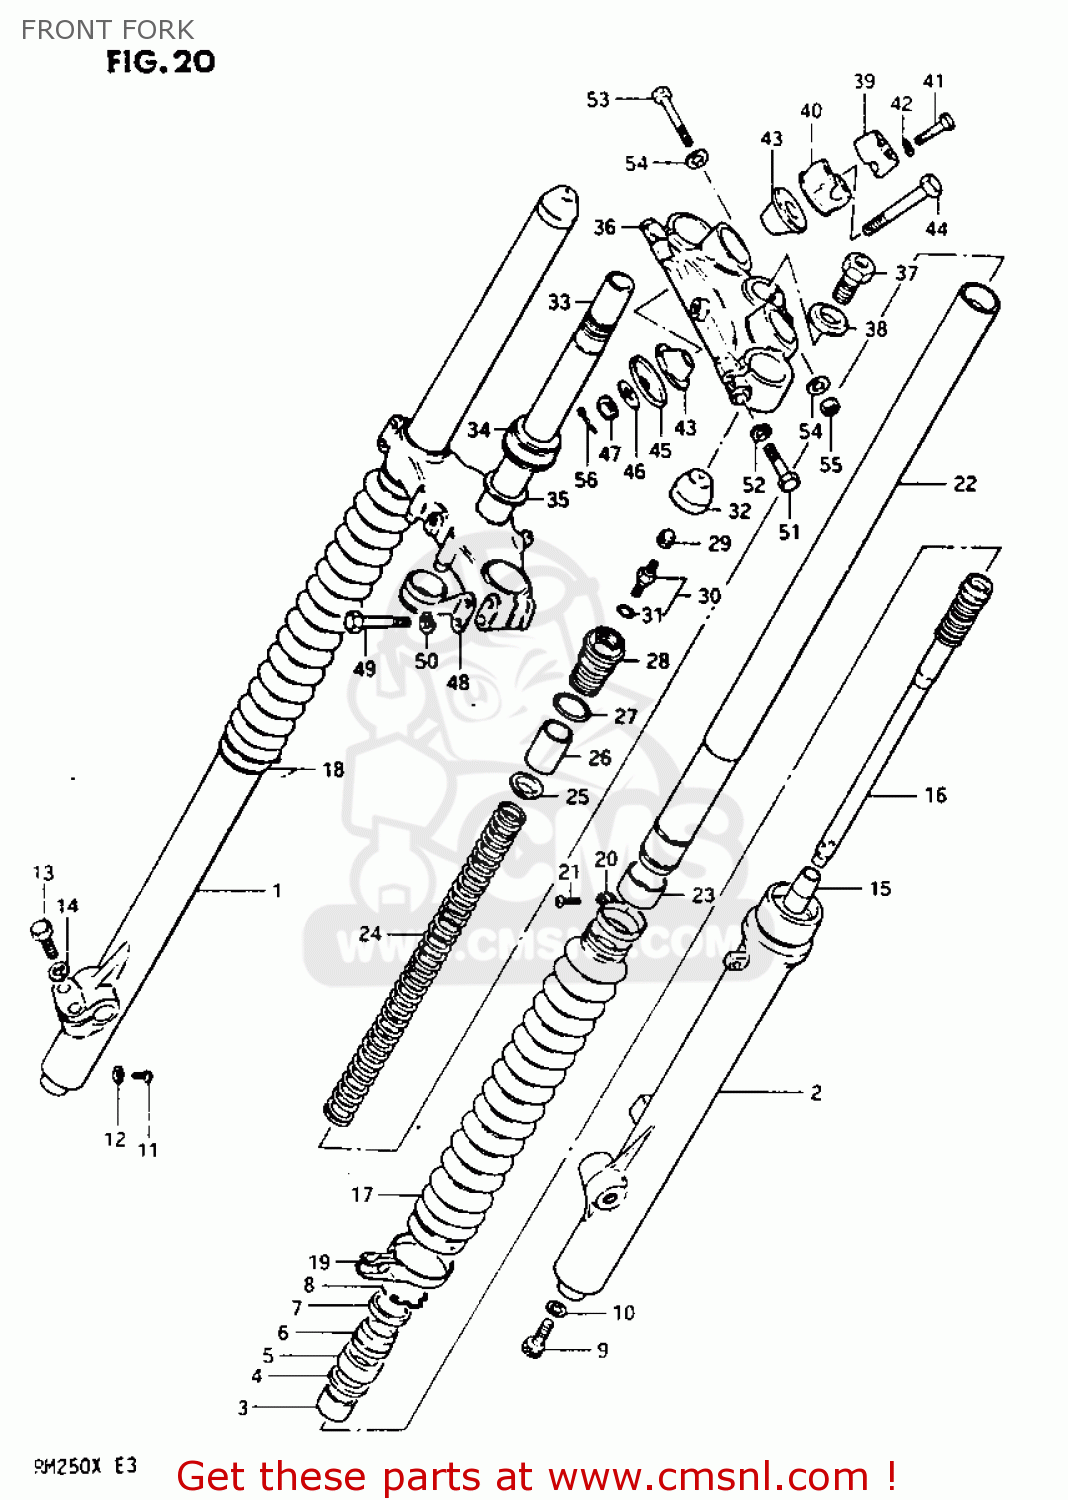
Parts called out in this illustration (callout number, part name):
1	DAMPER SET
2	TUBE,OUTER,LEFT
3	METAL,SLIDE
4	WASHER(40X50X2.3)
5	SEAL,OIL
6	SEAL,DUST
7	CASE,DUST SEAL
8	RING,STOPPER
9	BOLT,CYLINDER
10	GASKET,CYLINDER (NAS)
11	SCREW
12	GASKET,DRAIN,PLUG (NAS)
13	BOLT
14	WASHER,LOCK
15	PIECE,OIL LOCK
16	CYLINDER,FRONT FORK
17	BOOT
18	BAND,FRONT FORK COVER BOOT
19	BAND,FRONT FORK COVER BOOT
20	BAND,BOOT
21	SCREW
22	TUBE,FORK,INNER
23	PISTON
24	SPRING,FRONT FORK
25	GUIDE
26	SPACER,FRONT FORK SPRING
27	O RING
28	CAP,FORK INNER TUBE
29	CAP,VALVE AIR
30	VALVE
31	O RING
32	CAP
33	STEM,STEERING
34	BEARING(30X55X17)
35	WASHER,THRUST
36	HEAD,STEERING STEM
37	BOLT
38	WASHER
39	HOLDER,HANDLEBAR
40	HOLDER,HANDLEBAR,LOWER
41	BOLT
42	WASHER,LOCK
43	CUSHION,HANDLE HOLDER
44	BOLT,HANDLE HOLDER
45	COVER,HANDLEBAR HOLDER
46	WASHER,HANDLEBAR HOLDER
47	NUT
48	CLIP,CABLE
49	BOLT 8X45
50	WASHER,LOCK
51	BOLT
52	WASHER,LOCK
53	BOLT 8X50
54	WASHER
55	NUT
56	PIN 20X20
